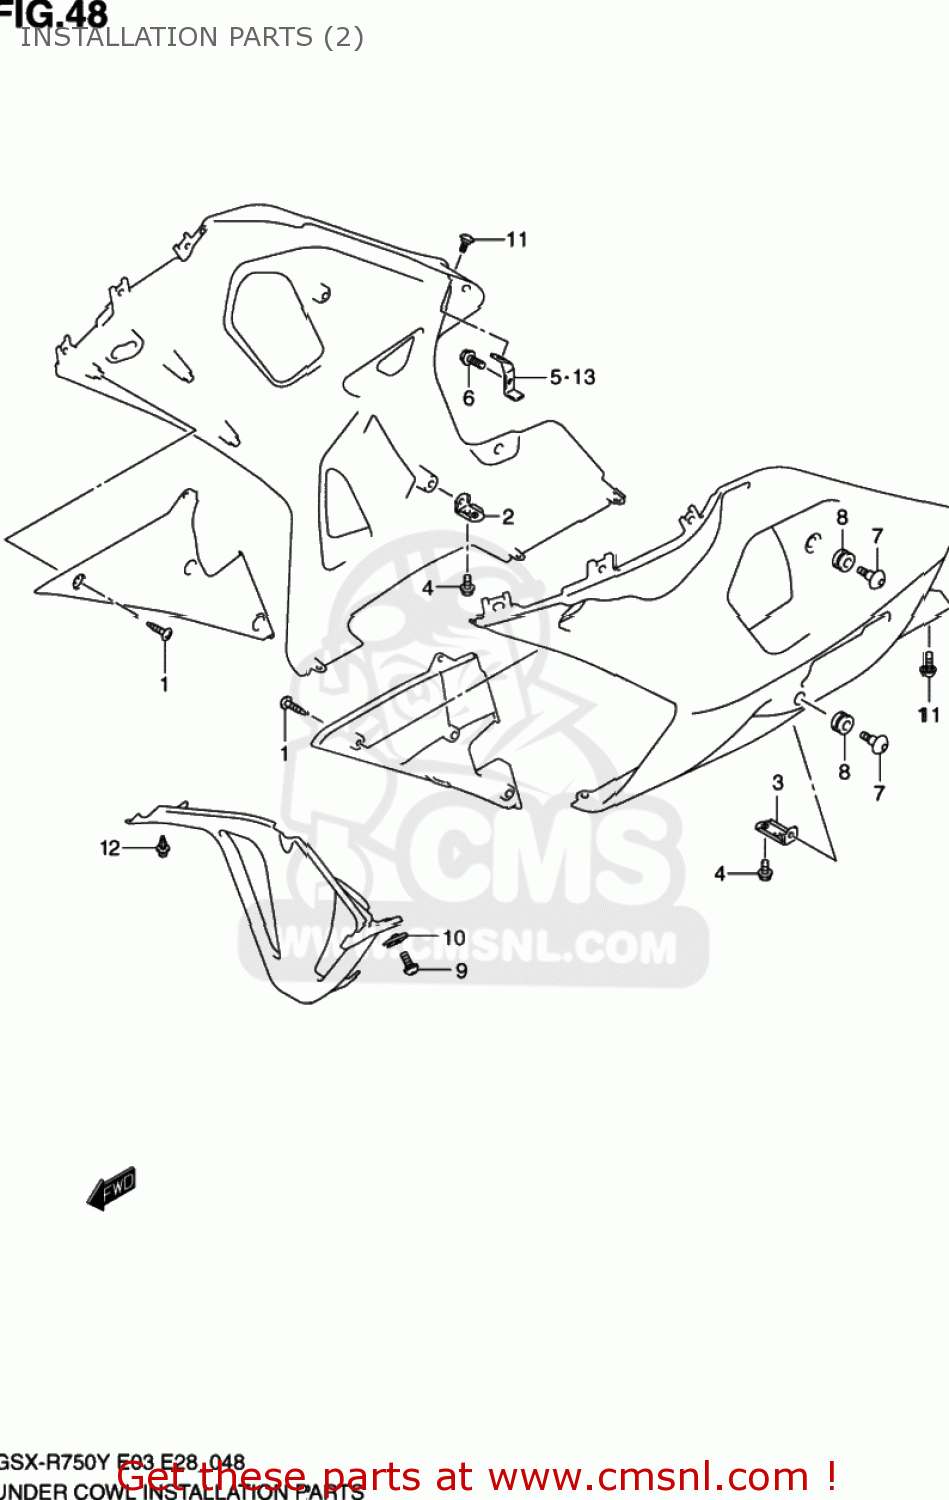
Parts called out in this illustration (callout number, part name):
1	SCREW
2	BRACKET,UNDER COWLING,LOWER
3	BRACKET,UNDER COWLING,LOWER
4	BOLT
5	BRACKET,UNDER COWLING UPR,R
6	BOLT
7	SCREW(6X20)
8	CUSHION
9	SCREW(5X13)
10	NUT,COWL
11	SCREW(5X13)
12	CLIP
13	BRACKET,UNDER COWLING UPR,L
